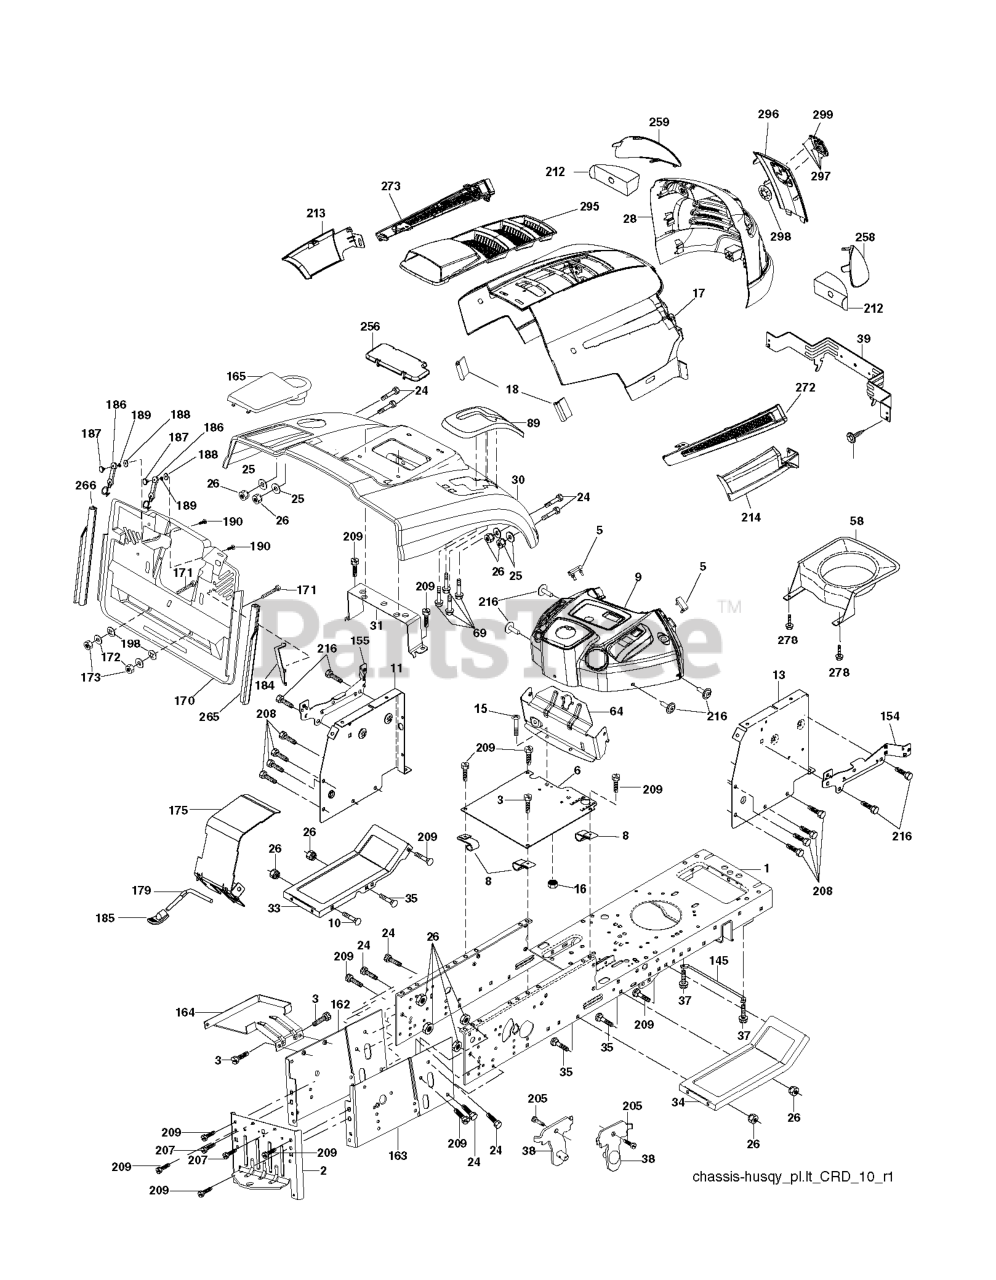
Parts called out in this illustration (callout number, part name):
2	DRAWBAR
3	SCREW 3/8-16X3/4
5	BUMPER DASH
6	PLATE
8	CLIP,INSULATOR
10	BOLT D
11	PANEL.DASH.LH.LTX
13	PANEL ASM, DASH RH
15	Screw, Machine, Truss Head 5/16-18 UNC x 3/4
16	NUT
17	HOOD
18	BUMPER.HOOD.TEX.HUSQVARNA
25	WASHER
26	NUT
28	RP GRILLE/LENS ASM.
30	CONSOLE.CRD.AUTO.GRY
31	BRACKET SUPPORT FENDER
33	FOOTREST PNT LH
34	FOOTREST PNT RH
37	Screw 5/16-18 x 1/2 Hex, Self Tapping 5/16-18 x 1/2
38	BRACKET ASM PIVOT MOWER REAR
39	BRACKET PIVOT
69	SCREW.HI-LO.CONSOLE
89	CONSOLE.CRD.AUTO.GREY.2005
145	ROD.PIVOT.HOOD
162	BRACKET
163	BRACKET EXTEN CHASSIS RH CRD
165	RP.COVER.BATTERY.CRD.GREY
172	WASHER
175	DOOR TRAP
179	ROD PIVOT FBI
184	BRACKET.ACTUATOR.BAGGER.SRD
186	LATCH ASSY
187	WELDNUT
189	LOCKWASHER #10
190	SCREW
207	SCREW, 5/16-18 X 1/2
208	SCREW 3/8-16X1/2
209	SCREW, 3/8-16X3/4
212	INSERT REFLECTIVE
213	SKIRT SIDE LH
214	SKIRT SIDE RH
216	SCREW HEXWSHR 1/4-20X3/4
256	COVER FENDER CRD
258	LENS.HUSQVARNA LT.RH
259	LENS.HUSQVARNA LT.LH
265	SEALING
266	SEALING
272	VENT SIDE HOOD RH
273	VENT SIDE HOOD LH
278	SCREW
295	VENT TOP HOOD
296	TRIM
297	CLIP.RETAINER.TINNER.
298	NUT PUSH M
299	RP LOGO
